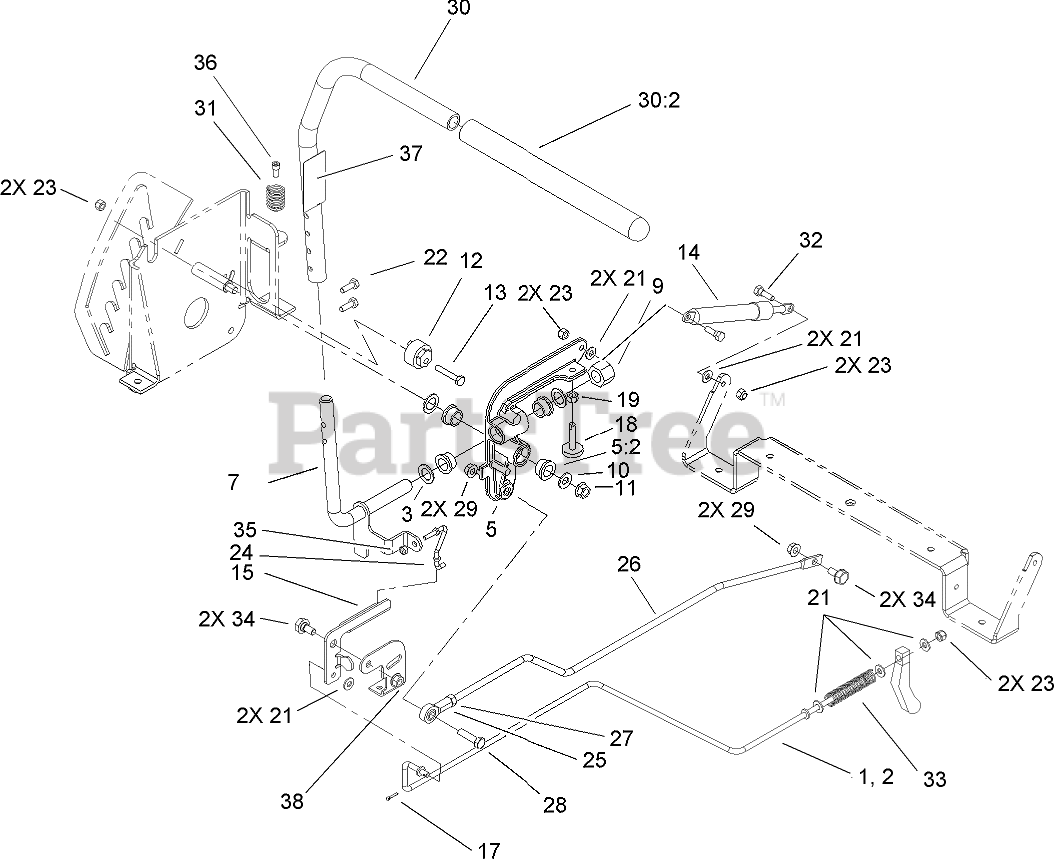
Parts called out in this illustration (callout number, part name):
1	ROD-BRAKE, LH
2	ROD-BRAKE, RH
3	WASHER-THRUST
5	RH ACTUATOR ARM W/BUSHING ASM
5:2	BUSHING
7	LH PIVOT SHAFT ASM
9	NUT-LOCK, NI
10	WASHER-FLAT
11	NUT-LOCK, NI
12	BUSHING-ECCENTRIC
13	SCREW-HH
14	Damper-Control, Motion
15	BELLCRANK
17	PIN-COTTER
18	STOP-ADJUSTMENT
19	NUT-HEX
21	WASHER-FLAT
22	SCREW-HH
23	NUT-LOCK, NI
24	LINK-BRAKE
25	BALLJOINT-RH
26	ROD-HYDRO
27	NUT-HEX
28	SCREW-HH
29	NUT-HF
30	HANDLE ASM
30:2	GRIP-CONTROL, MOTION
31	SPRING-COMPRESSION
32	BOLT-SHOULDER
33	SPRING-COMPRESSION
34	BOLT-SHOULDER
35	NUT-LOCK, NI
36	SCREW-HSH
38	NUT-HF
